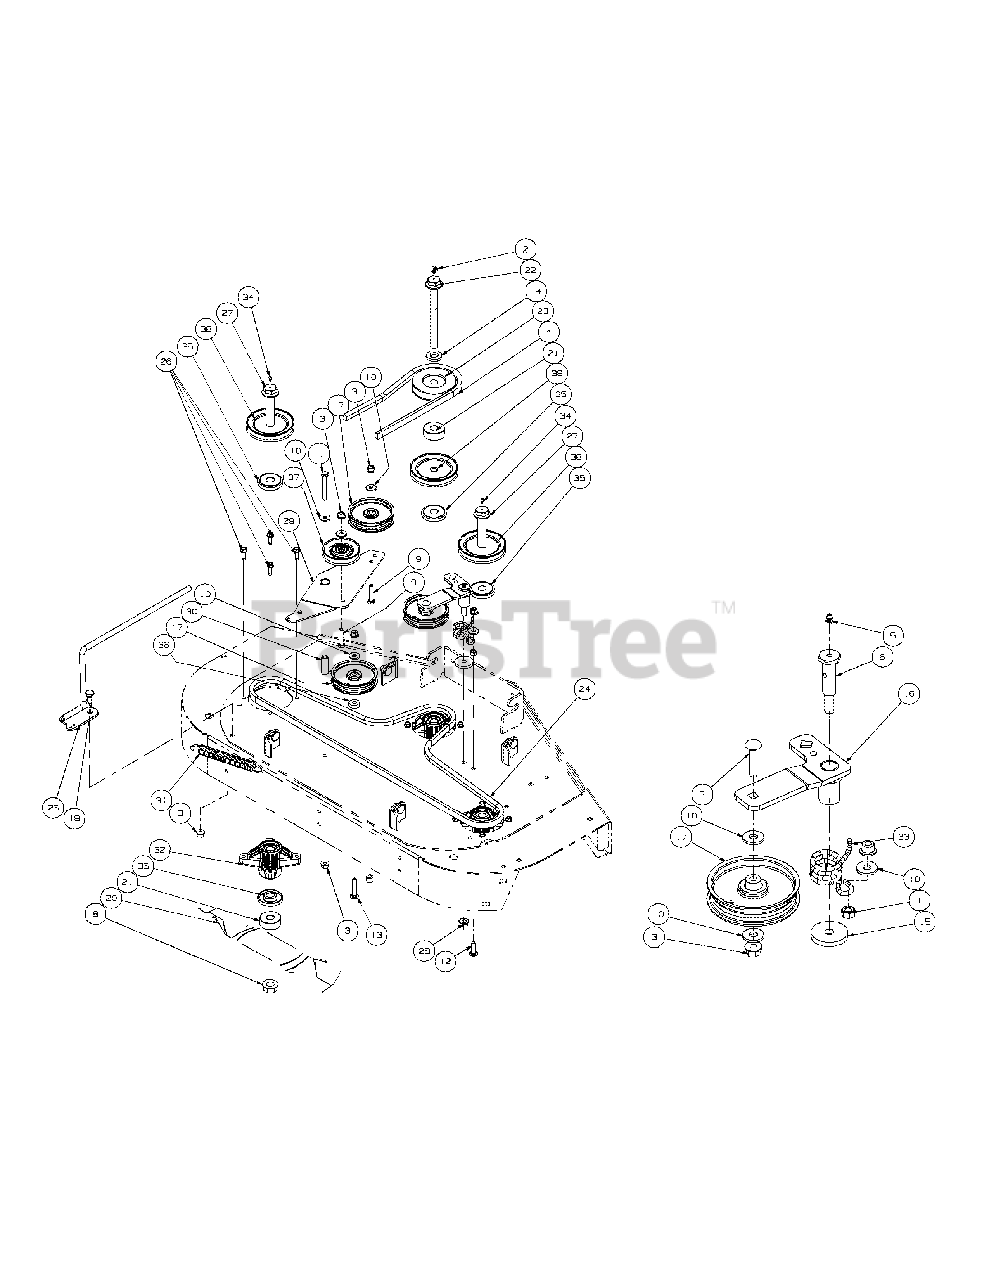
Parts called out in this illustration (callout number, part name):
1	Hex Nut 3/8-16
2	Grease Fitting, 90 degree
3	Hex Nut, 3/8-16 Flange Lock
4	Belt Drive
5	Grease Fitting, 1/4-28 x 3/16
6	Shoulder Screw, 7/16-14
7	Hex Carriage Screw, 3/8-16, 1.75
8	Hex Flange Nut, 3/4-16
9	Hex Cap Screw, 3/8-16 x 1.750
10	Flat Washer, .406 ID x 1.0 OD x .105
11	Hex Cap Screw 3/8-16 x 2.75
12	Carraige Screw, 3/8-16 x 1.25
13	Carriage Bolt, 3/8-16 x 2.00
14	Spacer, .812 ID x .218
15	Flat Washer, 7/16 ID x 1.75 OD
16	Idler Arm Assembly, Deck Spindle includes:
17	Flat Pulley
18	Shoulder Screw, .50 x .27, 3/8-16
19	Spacer, .625 OD x .385 ID x 1/2
21	Spacer .760 ID x 2.00 OD x 0.790
22	Spindle Bolt, 3/4-16 x 7.155
23	V-Pulley 4.25 OD Casting
24	V-Belt, A-Section
25	Spring Tension Rod Assembly
26	Self Tapping Screw 5/16-18 x 1.00
27	Spindle Bolt 3/4-16 x 5.37
28	Nut, 7/16-20, FlangeLock
29	Idler Arm Assembly, Double, includes:
30	Spacer, .39 ID x .625 OD x 1.875
31	Spring Extension, .98 OD x 5.00
32	Spindle Assembly
33	Idler Torsion Spring
34	Grease Fitting
35	Spindle Spacer
36	Spacer .406 ID x 1.0 OD
37	V-Pulley, 3.50 OD
